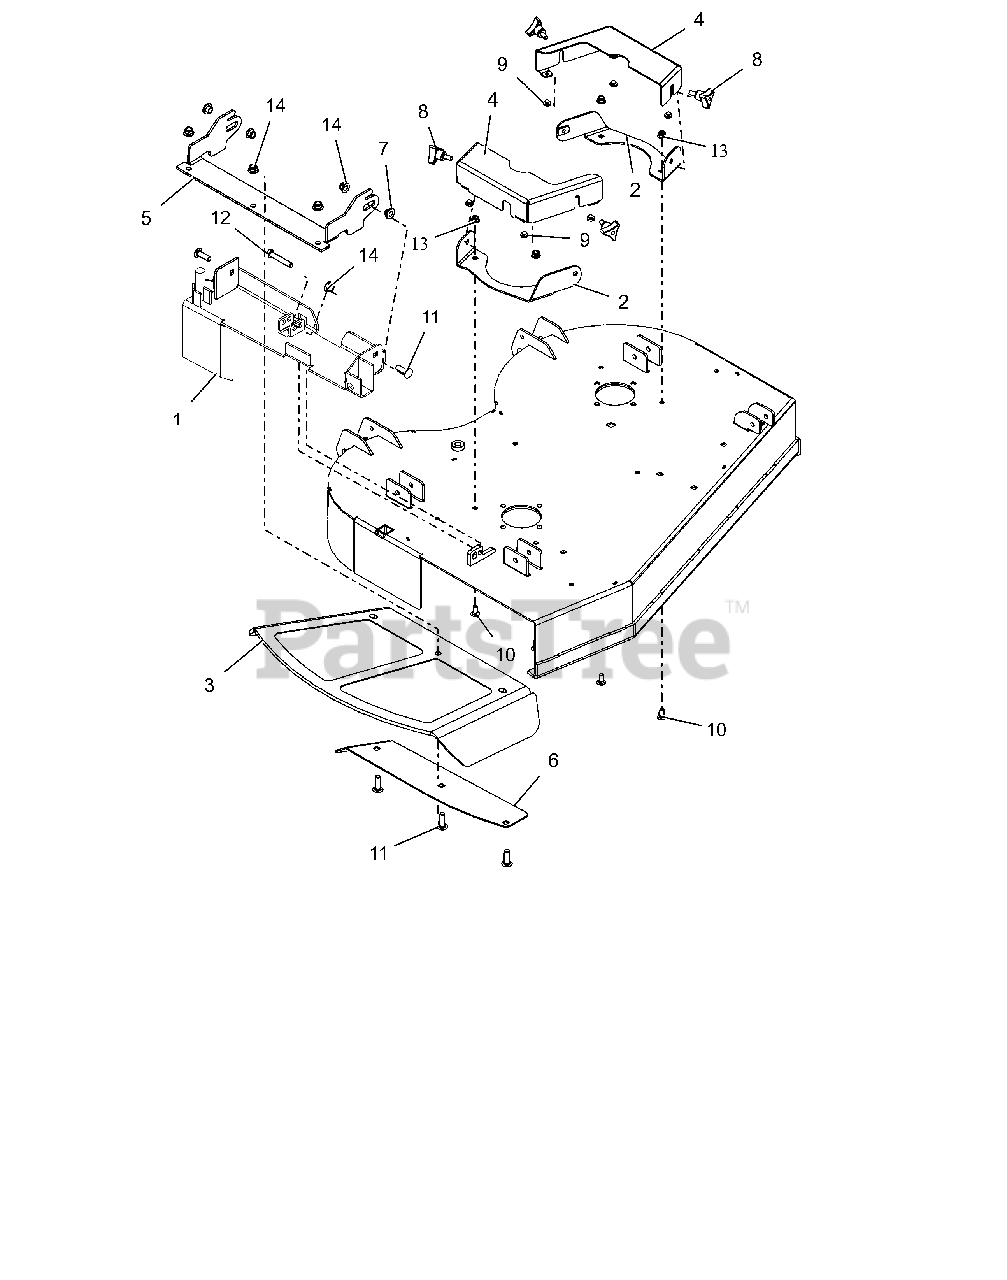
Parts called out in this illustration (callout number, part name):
1	WLDMT, DISCHARGE CHUTE (RED)
2	WLDMT, BELT GUARD MTG BRKT (RED)
3	CHUTE,48-60" FRMD RUBBER DISCH
4	GUARD, 36" DECK BELT (RED)
5	BRKT, 36" CHUTE MTG (RED)
6	PLATE, 36" DISCH CHUTE CLAMP (BLACK)
7	BSHG-FLG .385X.500X.875X.406
8	KNOB,WING STUD 5/16-18 X .75
9	BUMPER GROMMET
10	@BLT-RDHDSQNK .31-18X.75 G5YZ
11	@BLT-RHDSSQNK .38-16X1.25 G5YZ
12	@BLT-HEX .38-16X2.25 GR5 YWZC
13	@NUT-LK-NYL-FLG .31-18 YWZC
14	@NUT-LK-NYL-FLG .38-16 YWZC
